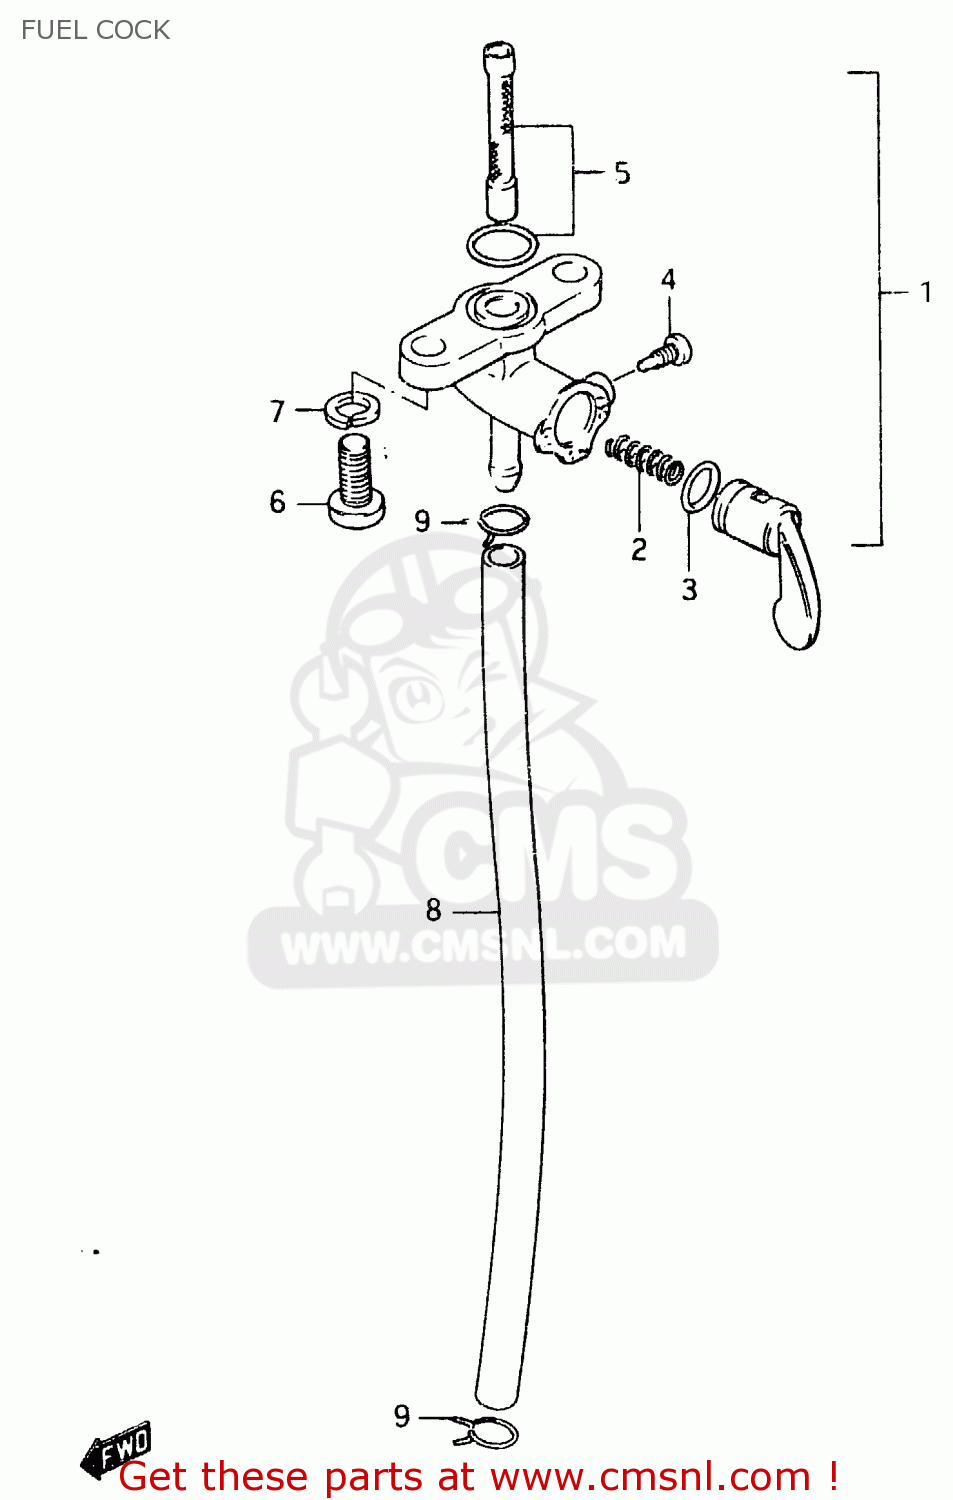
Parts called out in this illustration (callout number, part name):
1	COCK ASSEMBLY,FUEL
2	SPRING,FUEL COCK VALUE
3	O RING,LEVER
4	SCREW
5	FILTER SET FUEL
6	SCREW
7	LOCK WASHER
8	HOSE
9	CLIP
